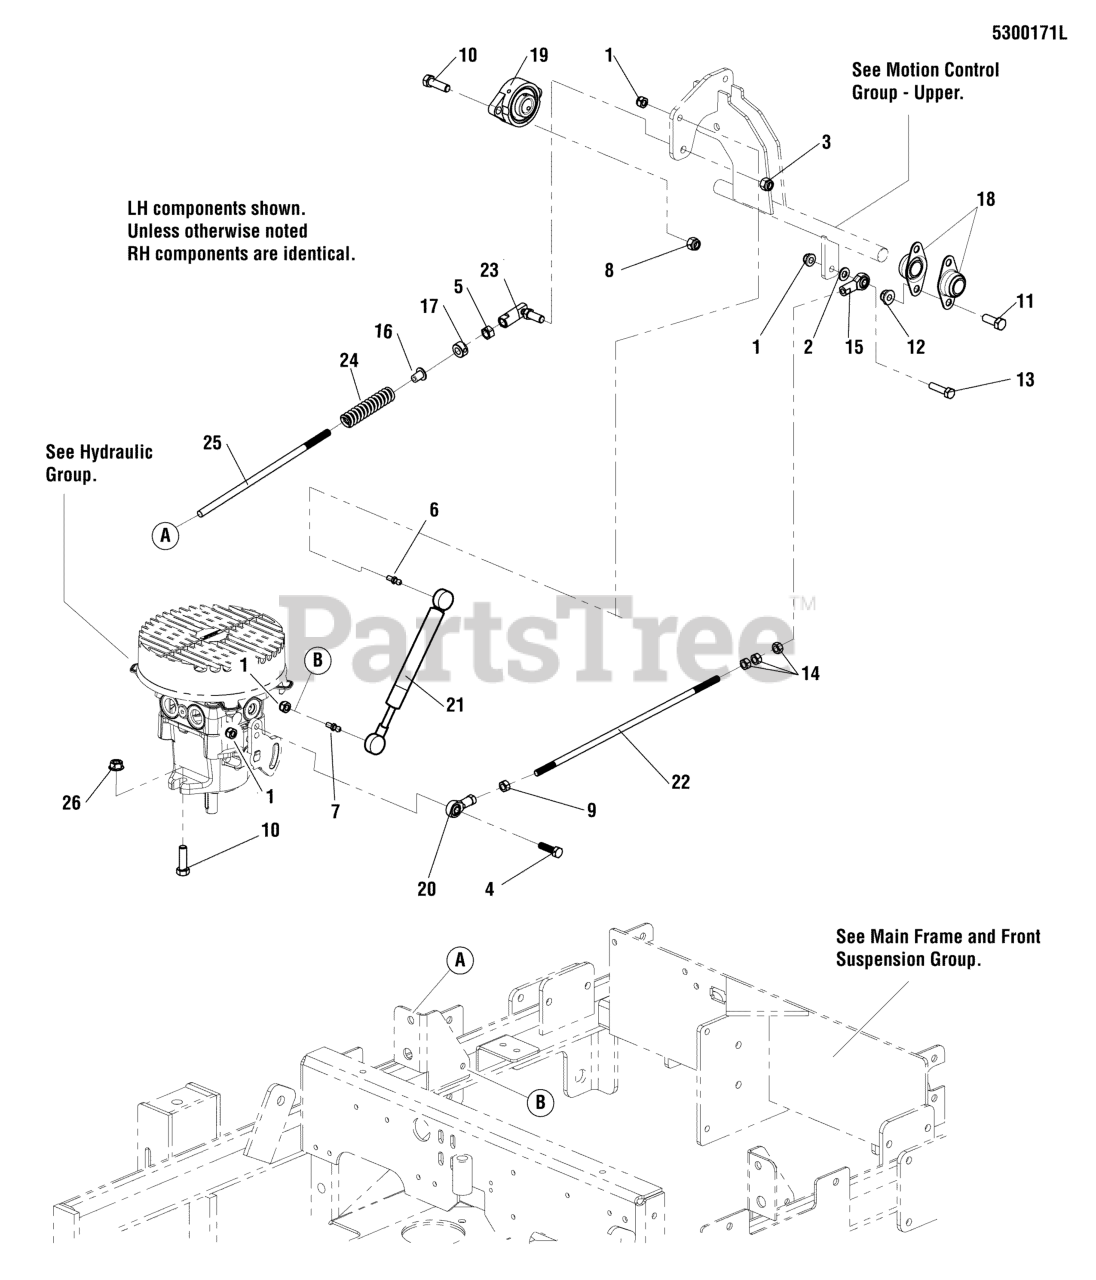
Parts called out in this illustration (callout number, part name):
1	NUT,5/16-18 HEX NYLOCK FLANGE
2	WASHER, 5/16" SAE
3	NUT, 3/8-24 HEX NYLON LOCK
4	BOLT, 5/16-18 X 1-1/8" GD5
5	NUT, HEX 3/8-24
6	BALL STUD, 5/16 X .75
7	BALL STUD, 5/16 X .50
8	NUT, 3/8-16 HEX NYLON LOCK
9	NUT, 5/16-24 HEX, LH
10	BOLT, 3/8-16 X 1-1/4" GD5 CZ
11	BOLT, 3/8-16 X 1" GD5 CZ
12	NUT, 3/8-16 HEX NYLOCK FLANGE
13	BOLT, 5/16-18 X 1-1/4" GD5
14	NUT, HEX 5/16-24
15	BALL JOINT 5/16-24 RH FEMALE BRONZE RACE
16	BUSHING, FLANGE, .375 X .469 X 1.500
17	COLLAR, 3/8" SET
18	BEARING, BRONZE FLANGE, 3/4"
19	BEARING, FLANGE
20	BALL JOINT 5/16-24 LH FEMALE BRONZE RACE
21	DAMPENER, CONTROL
22	ROD, HYDRO LINKAGE 3000
23	BALL JOINT, 3/8-24 FEM. STUD.
24	SPRING, REVERSE RETURN
25	ROD, NEUTRAL CONTROL
26	NUT, 3/8-16 HEX LG. SERR FLG
